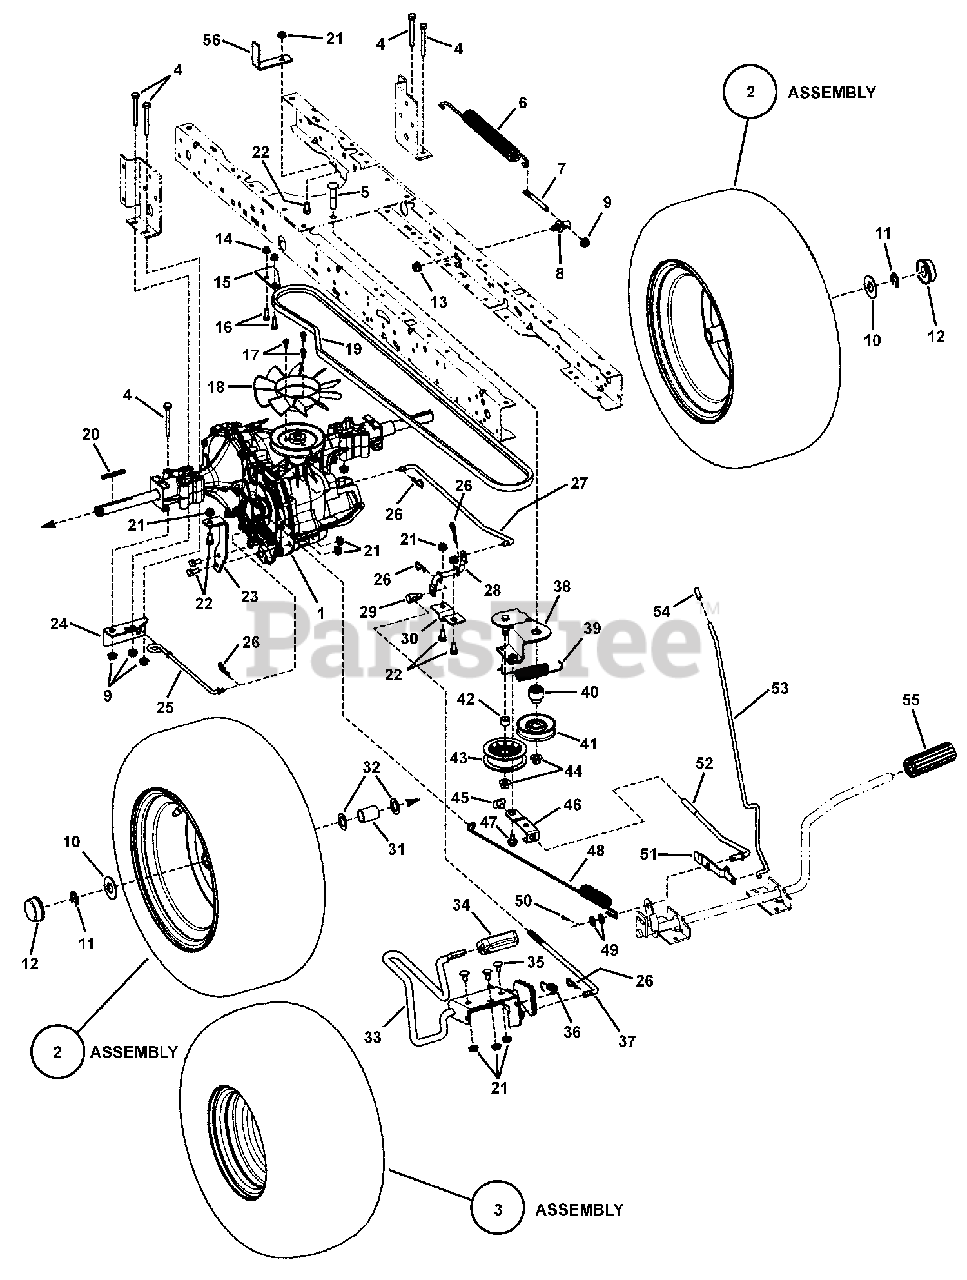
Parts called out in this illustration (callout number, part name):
1	TRANSAXLE, Hydro Gear #310-0510
1	TRANSAXLE, Hydro Gear #310-0610
2	ASSY, Wheel & Tire, 22 x 9.50-12 (incl. next 3 items)
3	ASSY, Wheel & Tire, 20 x 10-8 (incl. next 3 items)
4	BOLT, 5/16-18 x 2-1/2" Hex Head, GR 5
5	BOLT, 3/8-16 x 2 Square Neck Carriage
6	SPRING, Extension Lift
7	STUD, Spring Mounting (5/16-18)
8	STUD, Swivel (3/8-16)
9	NUT, 5/16-18 Hex Flange Lock, NC
10	FLAT WASHER, 1.862 x .765 x 16 GA
11	E-RING, .750D x .050 T
12	HUB CAP
13	NUT, 3/8-16 Hex Flange, NC
14	NUT, 1/4-20 Hex Flange Lock (Nyloc)
15	PLATE, Forward Stop
16	SCREW, 1/4-20 x 3/4 Hex Head Cap, GR 5
17	SCREW, #12-24 x 1/2" Hex Washer Self-Tap
18	FAN, 7.0 (Ten Blade)
19	BELT, Dual Spindle Brake
20	KEY, 3/16" Square x 2" long - Rear Wheels
21	NUT, 5/16-18 Hex Flange Ser YZ
22	BOLT, 5/16-18 x 5/8 Hex Head, GR 5
23	TORQUE BRACKET, Hydro
24	BRACKET, Roll Release
25	LEVER, Roll Release
26	HAIR PIN, .092 Dia.
27	ROD, Rear Drive
28	ROD, Pivot Drive
29	SWIVEL, Adjustment (3/8-24)
30	BRACKET, Support
31	SPACER, Axle
32	WASHER, Flat, 3/4 x 1-1/4 x 16GA
33	WELDMENT, Foot Control
34	PAD, Forward Foot
35	BOLT, 5/16-18 x 5/8" Square Neck Carriage, GR 5
36	SPRING, Extension
37	ROD, Front Drive (3/8-24)
38	WELDMENT, Idler Arm
39	SPRING, Clutch
40	PIVOT BUSHING
41	IDLER PULLEY, 3 Dia.
42	SPACER, 1/2 to 17mm
43	IDLER PULLEY, 2.75 Dia.
44	NUT, 3/8-16 Hex Flange, Zinc Plated
45	NUT-Tee, (3/8-16)
46	LINK, Clutch
47	SHOULDER BOLT, 1/4-20 x 3-3/4"
48	SPRING, Hydro Brake
49	WASHER, .390 ID x .75 OD Flat
50	PIN, .090 x 3/4 Cotter
51	LATCH - Parking Brake
52	ROD, Clutch Drive (3/8-16)
53	ROD, Parking Brake
54	GRIP
55	PEDAL, Clutch/Brake
56	GUIDE, Hydro Belt, Black Gloss
